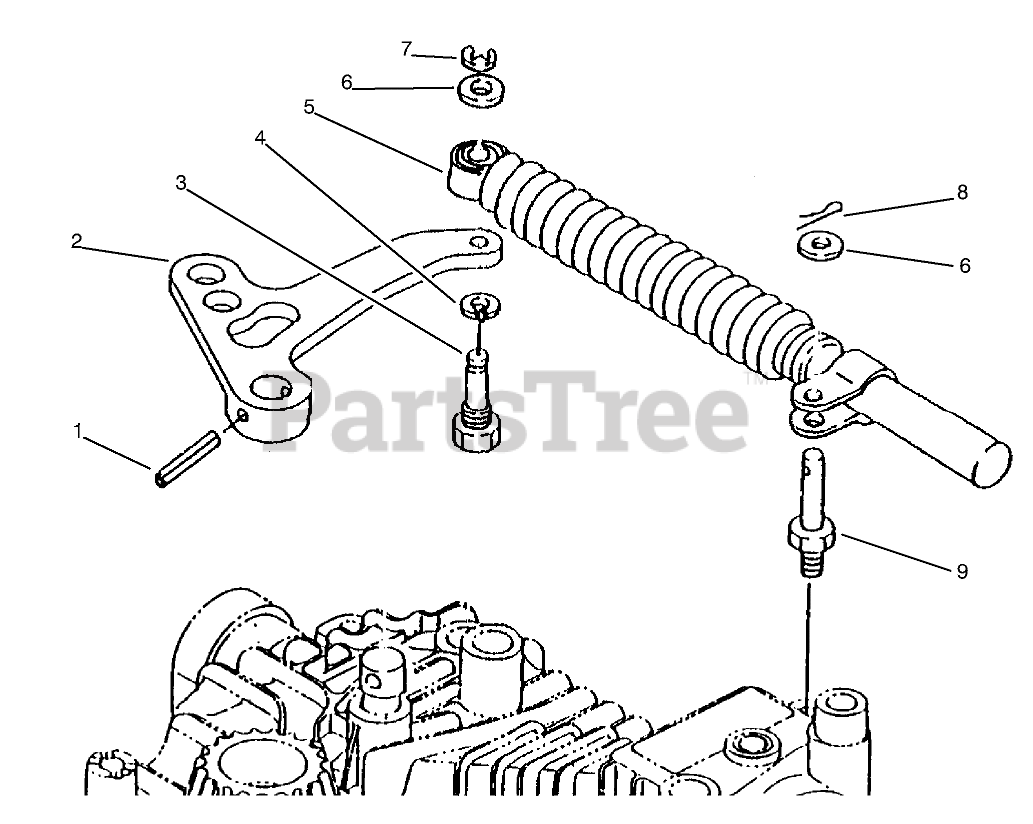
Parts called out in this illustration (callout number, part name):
1	PIN-ROLL
4	WASHER
5	ABSORBER - SHOCK
6	WASHER
8	PIN-COTTER
